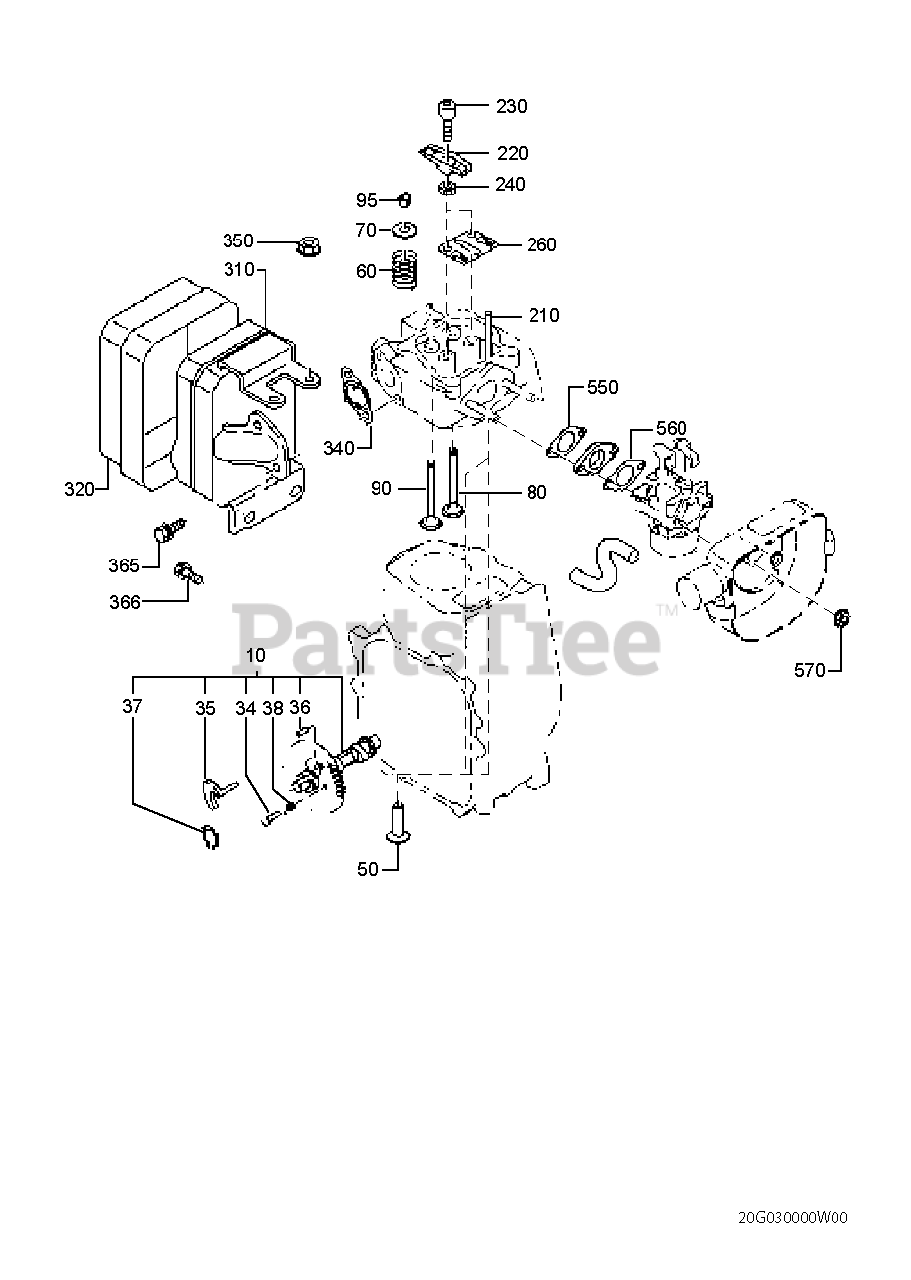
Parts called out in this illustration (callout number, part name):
70	SPRING RETAINER
340	GASKET (EXHAUST)
366	BOLT AND WASHER AY
550	GASKET (INTAKE)
